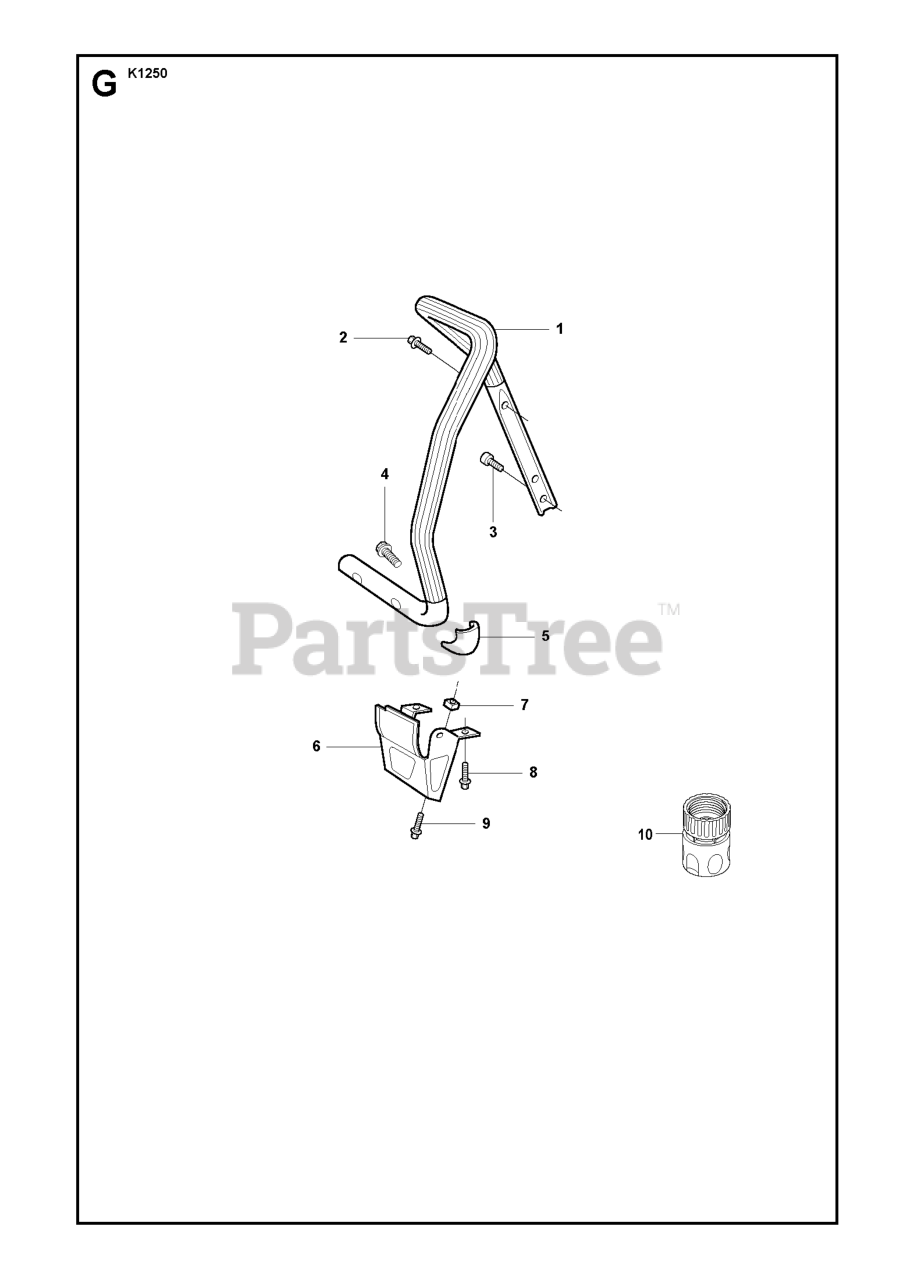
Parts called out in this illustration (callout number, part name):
2	SCREW
6	SUPPORT
8	SCREW MC6S 6X20
10	FEMALE QUICK COUPLER
